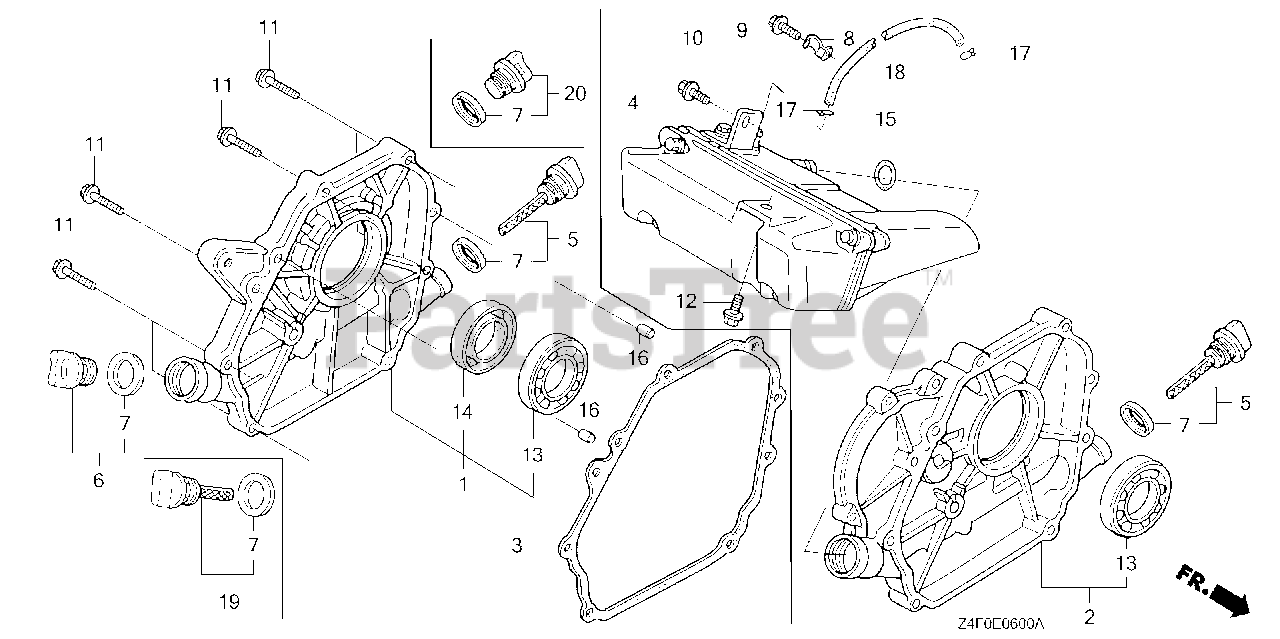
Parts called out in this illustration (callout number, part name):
1	COVER ASSY., CRANKCASE
3	GASKET, CASE COVER
5	CAP ASSY., OIL FILLER (GRAY)
6	CAP ASSY., OIL FILLER
7	GASKET, OIL FILLER CAP
11	BOLT, FLANGE (6X28) (CT200)
13	BEARING, RADIAL BALL
14	OIL SEAL (22X41X6)
16	PIN, DOWEL (8X14)
